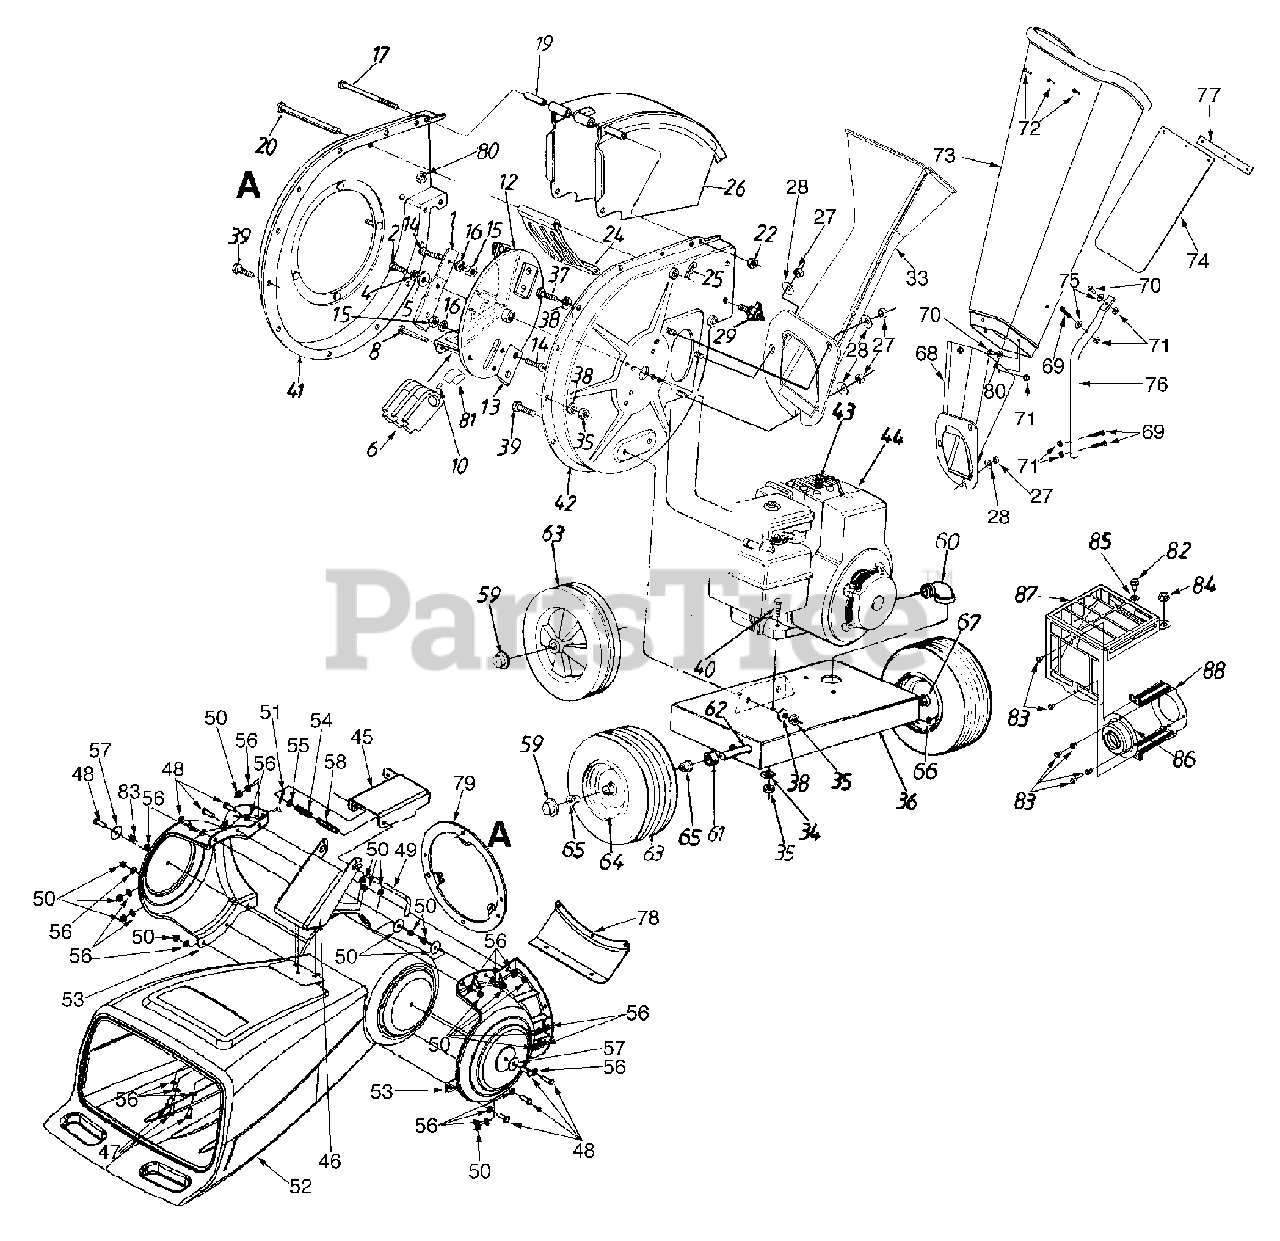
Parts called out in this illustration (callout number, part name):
1	Blade
2	Hx Patch Bolt 3/8-24 x 2.25" (Gr. 8)
4	L-Wash. 3/8" I.D. H.D.
5	Fl-Wash. .406" I.D. x 1.25" O.D. Hdn.
6	Flail Blade
8	Clevis Pin .496" Dia.
10	Spring Roll Pin 1.00" Lg.
12	Impeller Ass'y. Comp.
13	Chipper Blade
14	Flat Hd. Scr. 5/16-24 x .75" Lg.
15	Hex Top L-Nut 5/16-24 (Gr. 5)
16	L-Wash. 5/16" I.D.
17	Hex Bolt 1/4-20 x 3.75" Lg.
19	Chute Hinge Spacer 1.66" Lg.
20	Clevis Pin .5" Dia. x 4.62" Lg.
22	Hex Flg. L-Nut 1/4-20 Thd.
25	Internal Cotter Pin 3/8" Dia.
27	Hex Nut 5/16-18 Thd. (Gr. 5)
29	Hand Knob Ass'y.
34	Spec. L-Wash. 5/16" I.D.
35	Hex Nut 5/16-18 Thd. (Gr. 5)
37	Hex Bolt 5/16-24 x .75" Lg.
38	L-Wash. 5/16" I.D.
39	Hex Bolt 5/16-18 x .75" Lg. (Gr. 5)
40	Hex Bolt 5/16-18 x 1.50" Lg.
43	Spark Plug Boot
44	Engine
48	Hex Bolt 5/16-18 x 1.0" Lg. (Gr. 5)
49	Lock Rod
50	Hex L-Nut 5/16-18
51	Internal Cotter Pin .072 x 1.12 Lg.
52	Hopper
53	Collar-Hopper
54	Compression Spring
55	Flat Wash. 3/8 x .620 x .033
56	Flat Wash. .330 x .630 x .06
57	Flat Wash. .320 I.D. x 1.25 O.D.
58	Spacer .382 I.D. x .50 O.D. x 1.12
59	Push Cap 5/8" Dia. Rod
60	Drain Elbow
61	Spacer .64 I.D. x .38" Lg.
62	Shredder Axle
63	Wheel Ass'y. Comp.
66	Air Valve
67	Grease Fitting
70	Hex Bolt 1/4-20 x 0625
71	Lock Nut 1/4-20
72	Pop Rivet
73	Chipper Chute
74	Chute Flap
75	Flat Wash. .28 I.D.
77	Flat Strip
80	U-Nut
81	Spring Clip
82	Scr. TT. 1/4-20: .5"
83	Scr. AB 8-18:.375
84	Nut-Lock Hx. Flg. 5/16-18
85	Lockwasher
86	Deflector
87	Guard - Muffler
88	Bracket - Muffler Guard
